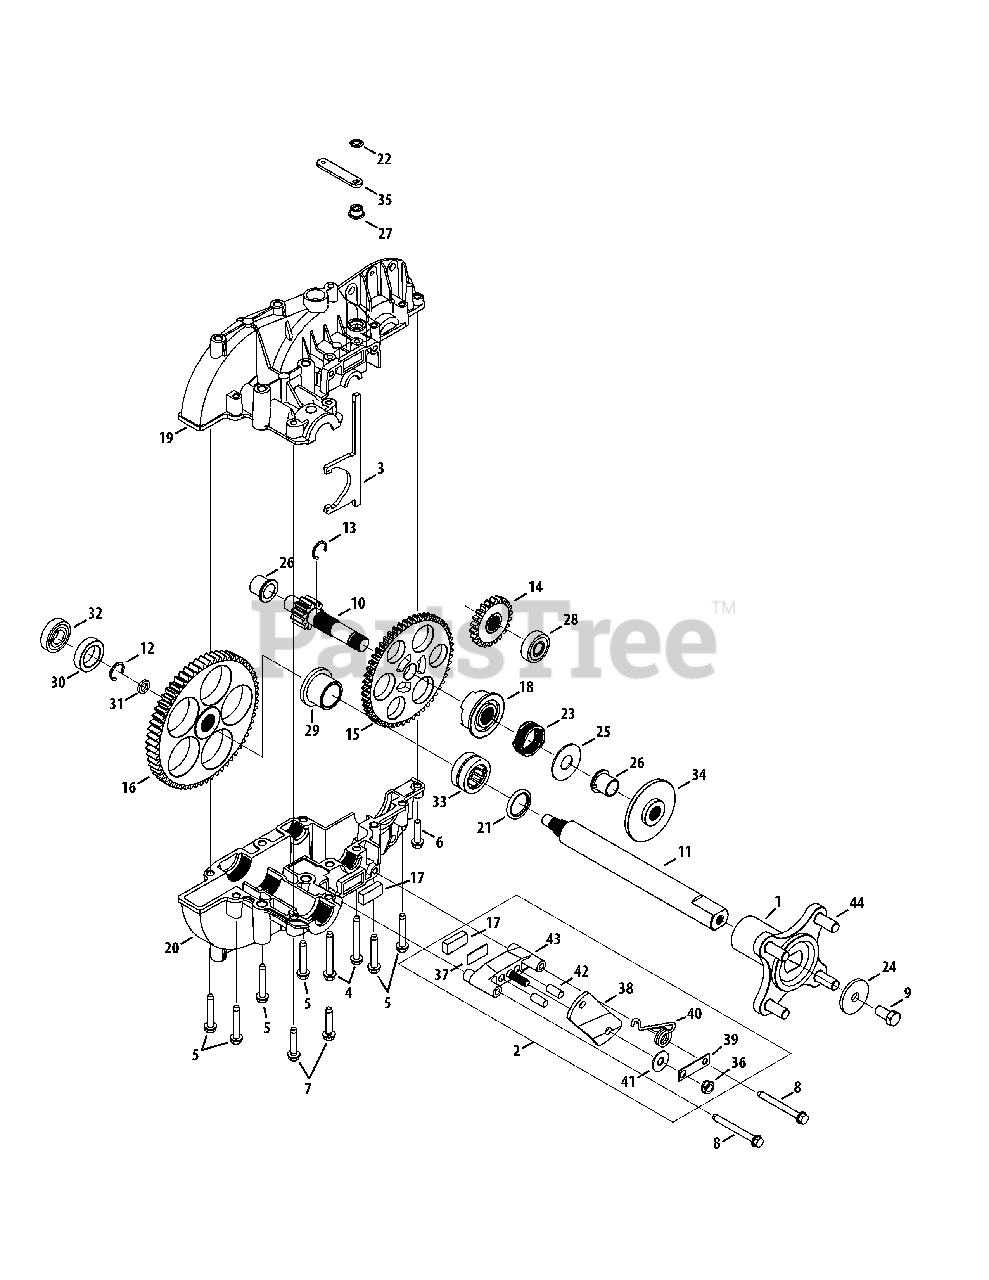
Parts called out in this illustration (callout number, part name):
1	Wheel Hub Assembly
2	Brake Ass’y, Yoke, RH
2	Brake Ass’y, Yoke, LH
3	Neutral Actuator
4	Screw, 1/4-20 x 2.00
5	Hex Washer Screw, 1/4-20 x 1.500
6	Hex Washer Screw, 1/4-20 x 1.000
7	Hex Washer Screw, 1/4-20 x 1.250
8	Hex Washer Screw, 1/4-20 x 2.375
9	Hex Cap Screw, 3/8-16 x .75
10	Electric Output Shaft, 11T
11	Axle Shaft
12	External Snap Ring
13	Retainer Ring, 7MM
14	Spur Gear, 22T
15	Spur Gear, 53T
16	Spur Gear, 61T
17	Brake Pad
18	Clutch Collor, U-Turn
19	Axle Housing
20	Axle Housing
21	Seal, 1.00 x 1.25 x .125
22	Push Nut, 1/4 x 17/32
23	Spring, 1.00 x 1.375 x .400
24	Flat Washer, .39 x 1.5 x .134
25	Flat Washer, 1.595 x .635 x .062
26	Flange Bearing, 5/8 x 3/4 x 3/4
27	Flange Slotted Bearing
28	Ball Bearing
29	Flange Bearing, 1.004 x 1.25
30	Thrust Bearing
31	Flat Washer, .632 x 1.00 x .160
32	Ball Bearing, .625 x 1.375 x 11/32
33	Bearing, 1.00 x 1.50 x .750
34	Brake Disc
35	Lever Plate
36	Hex Lock Nut, 5/16-24
37	Puck Plate
38	Arm, Brake Actuator - RH Brake
38	Arm, Brake Actuator - LH Brake
39	Anti-Rotation Brkt.
40	Torsion Spring, .75 OD x 3 Coils, RH
40	Torsion Spring, .75 OD x 3 Coils, LH
41	Flat Washer, .343 x .880 x .062
42	Brake Actuating Pin
43	Brake Yoke
44	Stud, rib Neck, 7/16-14 x 1.6
